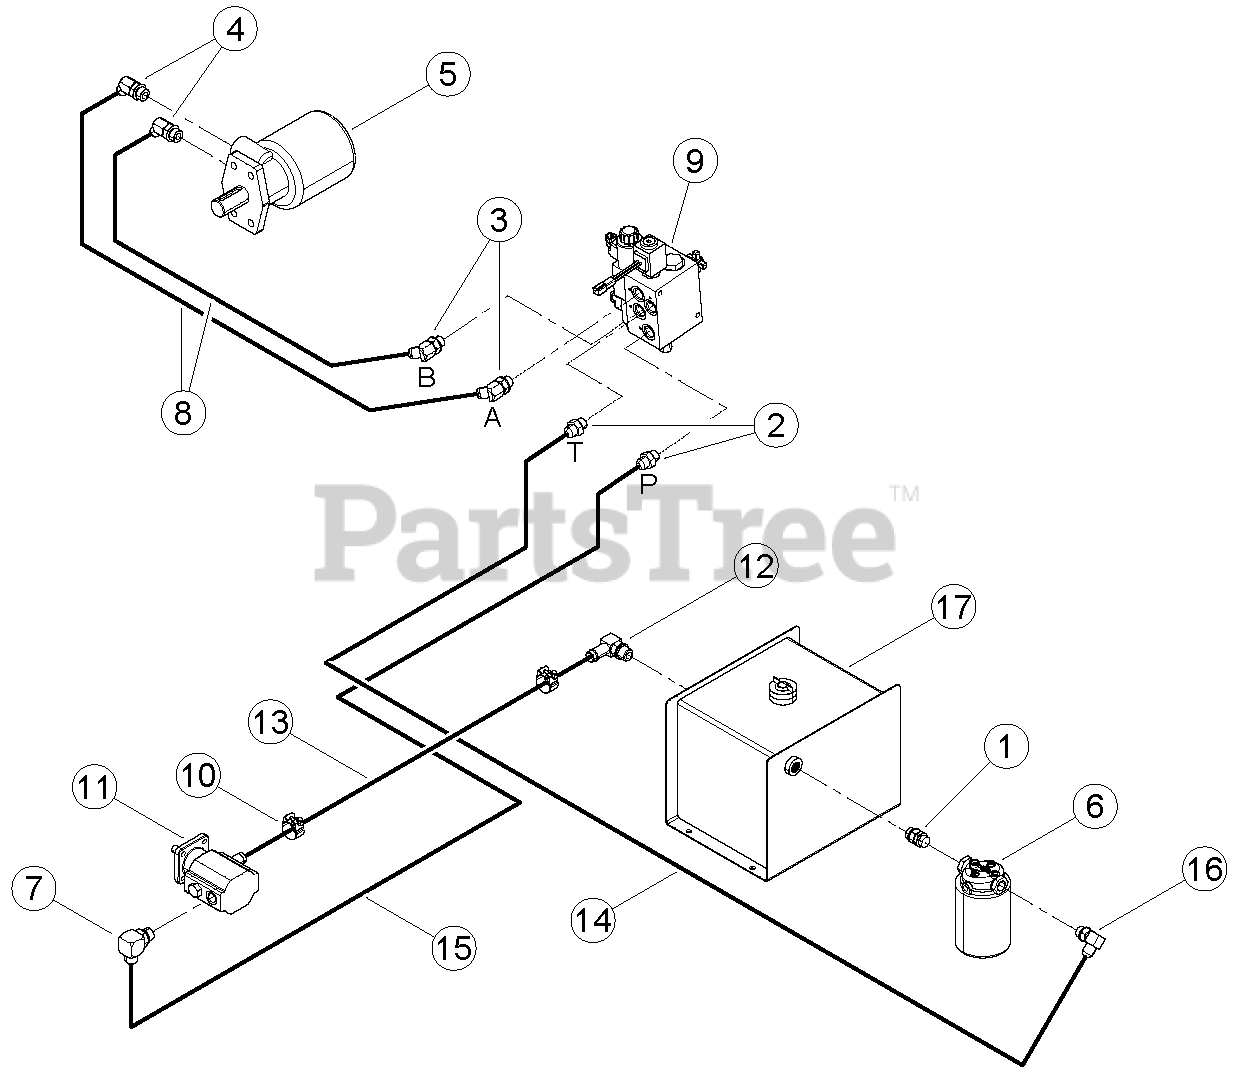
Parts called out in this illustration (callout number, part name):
1	ADAPTER, -8 MORING / -8 MORING ADJ
2	ADAPTER, -8 MORING / -8 MJIC
3	ADAPTER, -8 MORB / -8 MJIC 45 DEG.
4	ADAPTER, -10 MORING / -8 MJIC 45 DEG.
5	MOTOR, 45 CU. IN. HYDRAULIC
6	FILTER, SPIN-ON
7	CLAMP, 1-1/4 HOSE
8	ADAPTER, -10 MORING / -10 MJIC 90 DEG.
9	HOSE, .375 X 36 -8 FMJIC / -8 FMJIC
10	ASSEMBLY, CHIPPER VALVE
11	PUMP, PB CW HI/LO .646 DISP.
12	ADAPTER, -10 MORING / .75 90 DEG.
13	HOSE, .75 ID. X 38 IN. 100R4 HYD.
14	HOSE, .50 X 84 -8 FMJIC / -8 FMJIC
15	HOSE, .50 X 66 -8 FMJIC / -10 FMJIC 90 DEG.
16	ADAPTER, -8 MORING / -8 MJIC 90 DEG.
